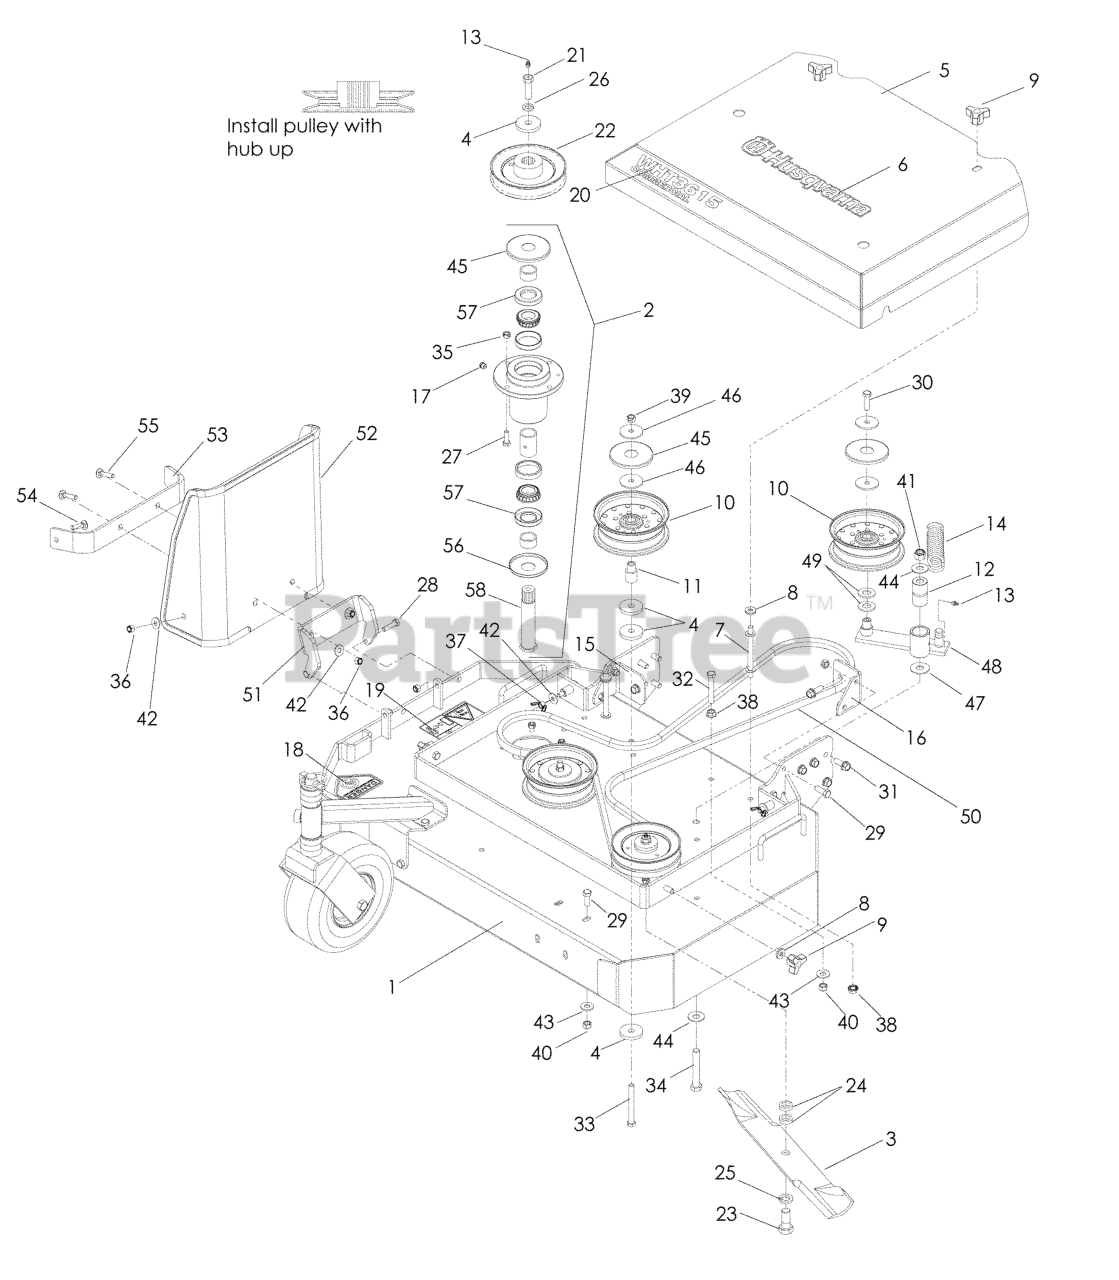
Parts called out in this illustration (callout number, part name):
1	DECK W/DECALS 36"WSL
2	SPINDLE ASM KIT, WHT/KIKW
3	BLADE OEM 18"
4	SPINDLE WASHER
5	BELT SHIELD, 36" ORANGE
6	DECAL, HUSQ 15" BLUE
7	SHIELD SPACER
8	WASHER, 3/8 SEALING
9	KNOB, THREE PRONG
10	IDLER PULLEY (TALL)
11	IDLER BUSHING
12	PIVOT BUSHING
13	ZERK
15	DECK SLIDE, RT
16	DECK SLIDE, LT
17	PLUG-VENTED
18	DECAL, CPSC
19	DECAL, EURO SEVERING
20	DECAL WH3615
21	HCS 7/16-20 GD 8 SPEC
22	PULLEY, 52
23	HCS 5/8-18X1-1/2 GR5 TPBLT ZD
24	BLADE SPACERS
25	LOCKWASHER 5/8
26	WASHER 7/16 LOCK
27	HCS 5/16C X 1
28	HCS 5/16C X 1 1/4
29	HCS 3/8-16X1.GRD.5.ZD
30	HCS 3/8C X 1 1/4 GR5
31	4CS 3/8C X 1 SERRATED HEAD
32	HCS 3/8C X 2 1/2
33	HCS 3/8-16 X 3-1/2 GR5 ZD
34	HCS 1/2C X 3 1/4
35	NUT 5/16C CENTERLOCK
36	NUT 5/16 NYLOC
37	WINGNUT, 5/16C NYLOC
38	NUT 3/8C WHIZ
39	NUT 3/8C CENTERBLOCK
40	NUT 3/8-16 NYLOC
41	NUT 1/2-13 HEX NYLOC ZD
42	WASHER 5/16 FLAT
43	WASHER 3/8 FLAT
44	WASHER 1/2 FLAT
45	TOP DUST CAP
46	WASHER, 3/8 SPEC
47	WASHER 1/2 X 1.44 HRD ZD
48	IDLER ARM-ANGLED, BLACK
49	WASHER 5/8 FLAT
50	BELT - 97.5", WRAPPED
51	PIVOT BRACKET - CHUTE
52	CHUTE, RUBBER DISCHARGE WB
53	BRKT, REINF-CHUTE WB
54	BOLT, CARRIAGE 5/16X1-1/4
55	RHSNB 5/16-18 X 1-1/2 GR 5 ZD
56	BOTTOM DUST CAP
57	SHAFT SEAL
58	SPINDLE 52/61
